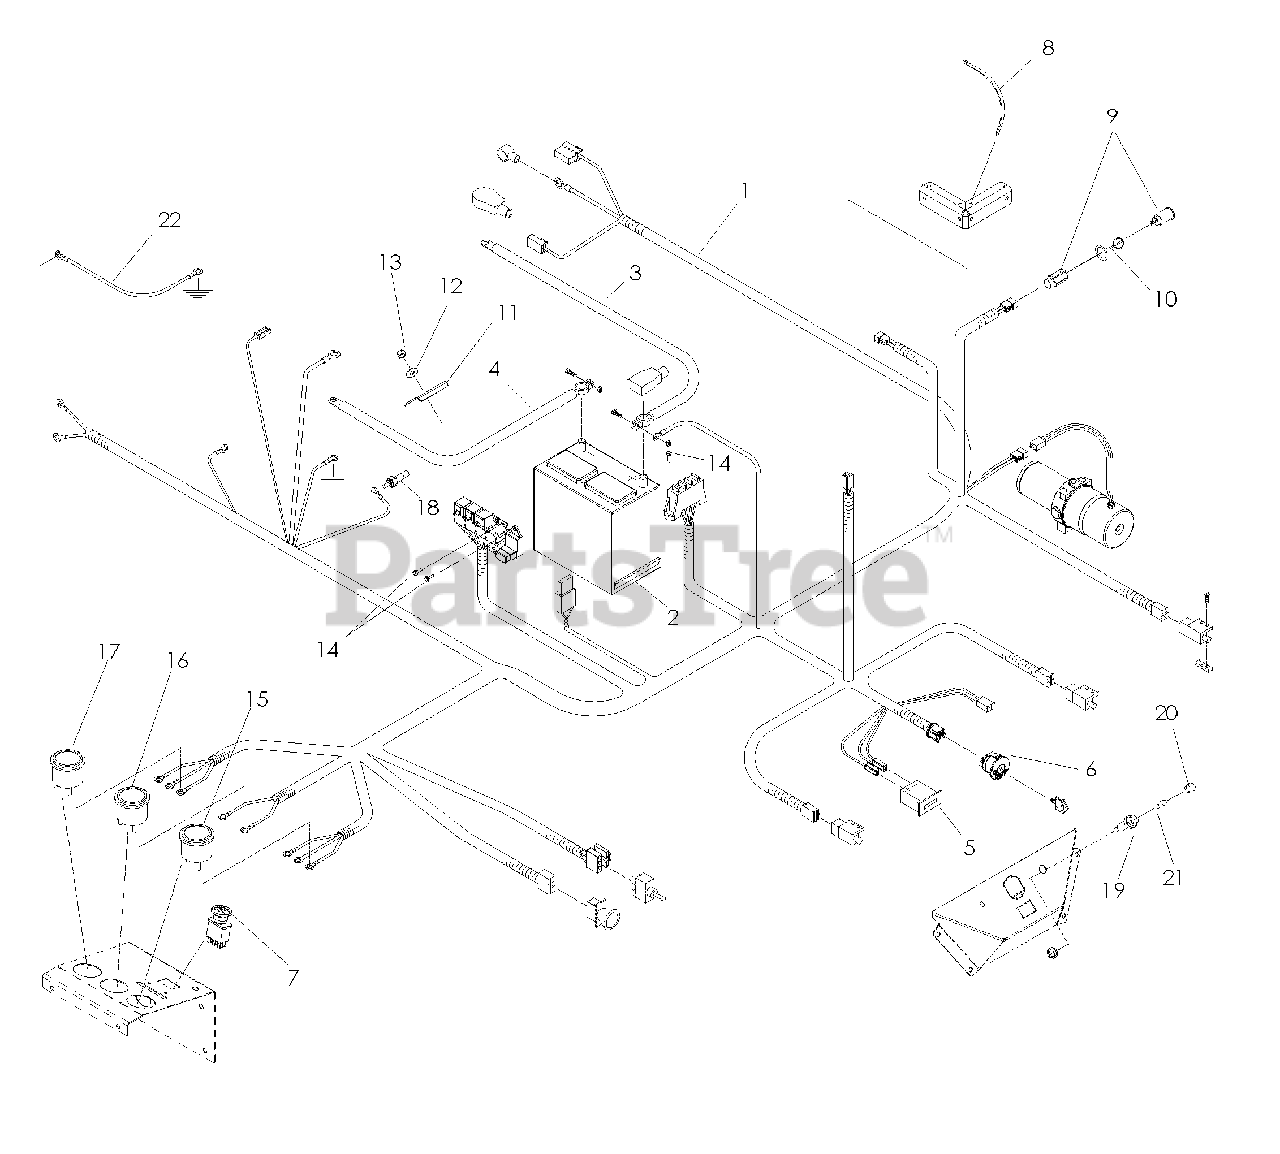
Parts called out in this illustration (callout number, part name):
3	CABLE, POSITIVE
4	CABLE, NEGATIVE
5	HOUR METER
6	IGNITION SWITCH
7	SWITCH, 10 AMP PTO
9	HOUSING, POWER SOURCE
10	CAP, POWER SOURCE
12	WASHER 5/16 STD FLT
13	NUT 5/16-18 HEX NYLOC
14	SCREW 10-12 x 3/4 THD FRM
15	GAUGE, TEMP
16	GAUGE, AMPERES
17	GAUGE, OIL PRESSURE
18	SENDER, TEMPERATURE
19	LAMP SOCKET
22	GROUND WIRE
